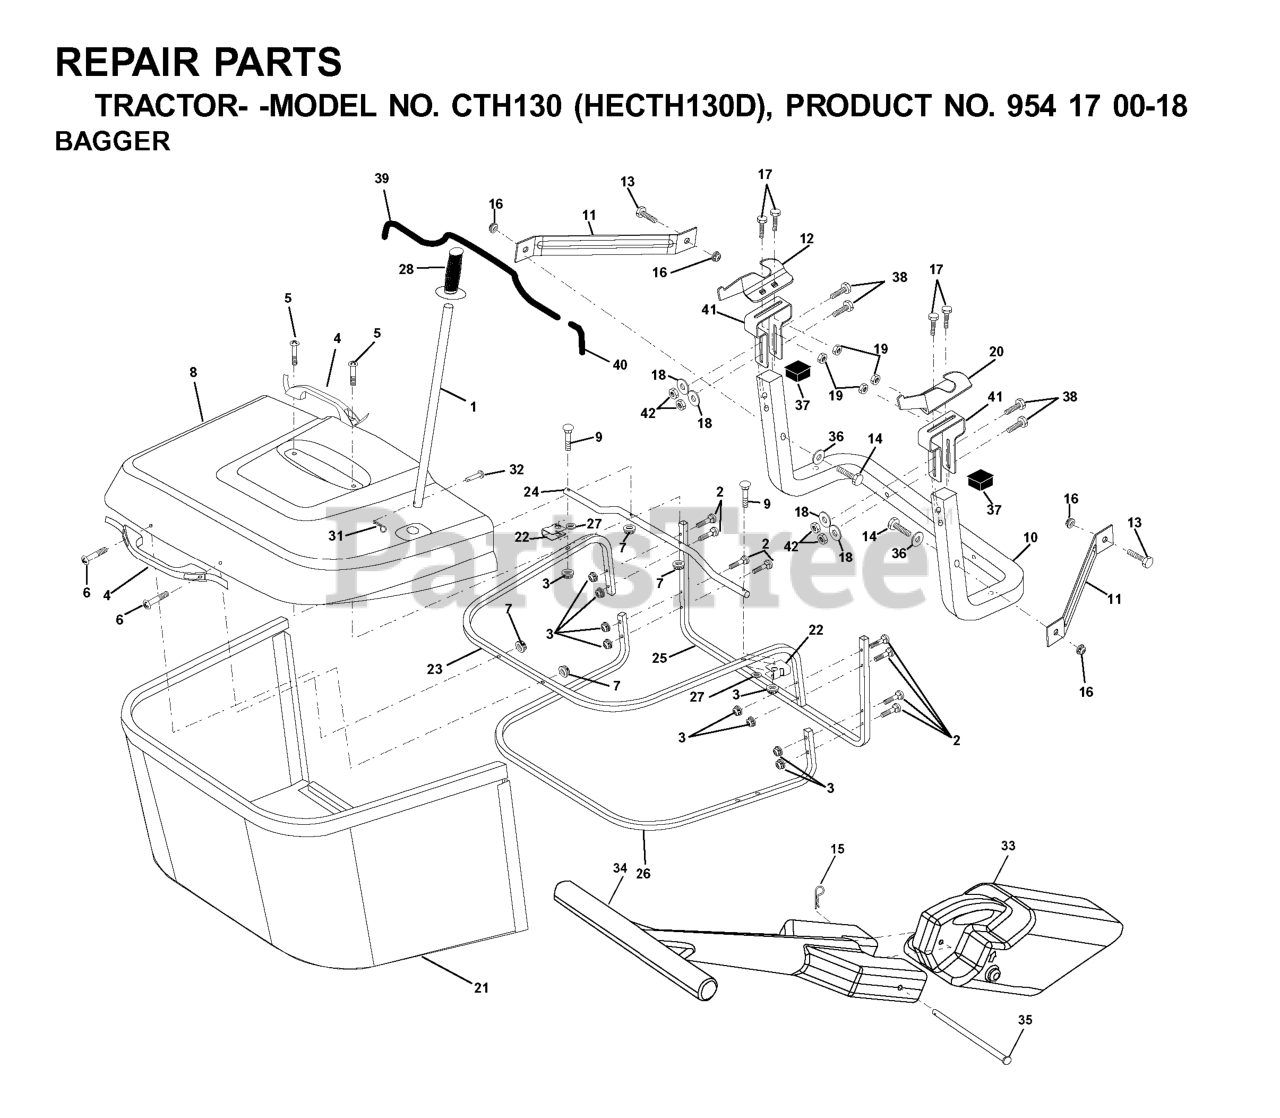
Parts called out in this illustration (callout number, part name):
1	TUBE HANDLE BAGGER
2	Bolt Carriage 1/4-20 x 2.0 Gr.5
3	NUT T
4	HANDLE.BAGGER.W/LVRS.BLK.CRD
5	SCREW.PAN.HEAD
6	REPL BY 532 75 00-29
8	COVER
9	Bolt Carriage 1/4-20 x 2.25d x Gr.5
10	TUBE
11	BRACKET.SUPPORT.UPPER.BAG.CRD
14	Bolt Hex 3/8-16 x 2-1/2 Gr. 5
15	RETAINER-SPRNG RB
16	NUT LOCK FLG 3/8-16 UNC
17	RP BOLT 5/16-18 X3/4 ZN/YEL GR
18	WASHER M
19	NUT LOCK HEX FLANGE 5/16-18
20	BRACKET
21	BAG
22	BRKT.SIDE.BAG.CRD
23	TUBE.UPPER.BAG.CRD
24	TUBE.PIVOT.BAG.CRD.BLACK
26	TUBE.LOWER.BAG.CRD
28	Grip Handle Black
31	RETAINER M
32	RIVET,DRILLED
33	PLUG.MULCHER.92 CRD
34	HANDLE.MULCHER.92.CRD (2 2)
36	WASHER
37	Plug Support Bagger CRD
38	BOLT.5/16-18X2.5
39	TRIM
40	TRIM
41	BRKT.VERT.ADJ.BAGGER.CRD
42	NUT.71038.31-18.HEX.NYLOCK
